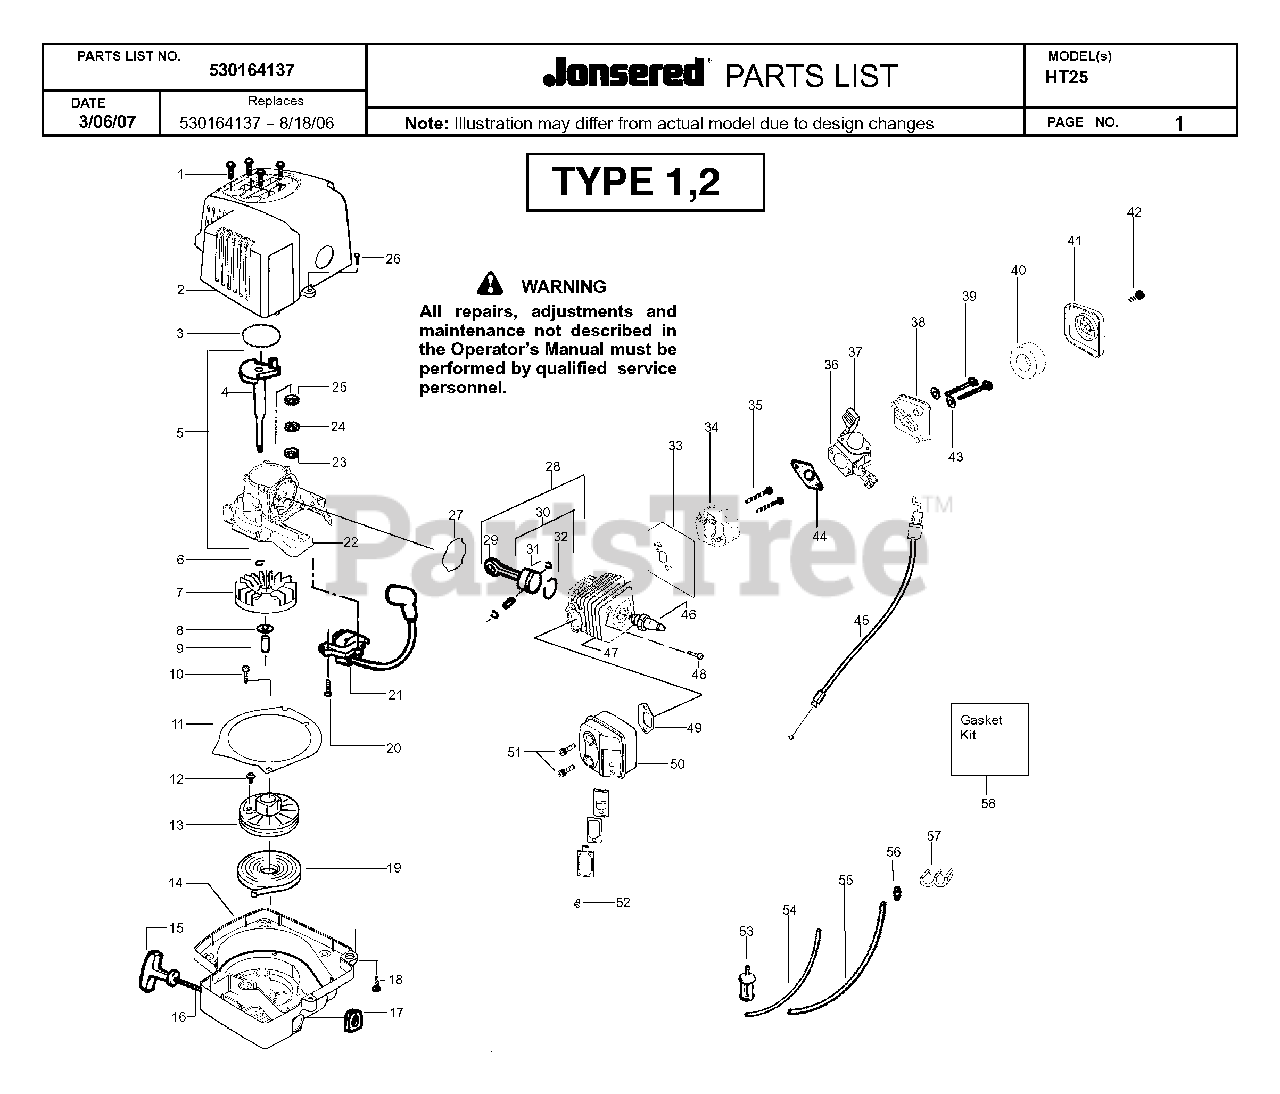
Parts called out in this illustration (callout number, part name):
2	ASSY-SHROUD
3	GASKET KIT
4	CRANKSHAFT ASSY
5	CRANKCASE
6	RETAINING RING
7	FLYWHEEL
8	WASHER FLAT
10	SCREW-10-16 X 1/2 HI-LO
11	PLATE-BAFFLE
13	STARTER PULLEY
15	HANDLE-STARTER
19	STARTER SPRING
21	IGNITION MODULE
22	CRANKCASE
23	OUTER BEARING
25	BEARING
27	GASKET KIT
28	PISTON KIT
30	PISTON KIT
31	WRIST PIN RET.
32	PISTON RING
33	GASKET KIT
41	AIR FILTER COVER
43	WASHER
44	GASKET KIT
45	THROTTLE WIRE
46	PLUG-SPARK (RCJ-6Y)
49	GASKET KIT
51	SCREW MUFFLER
52	SCREW-6-19X5/16PLAST PA
53	ASSY-FUEL PICK-UP
56	FUEL LINE FITTING
58	GASKET KIT
